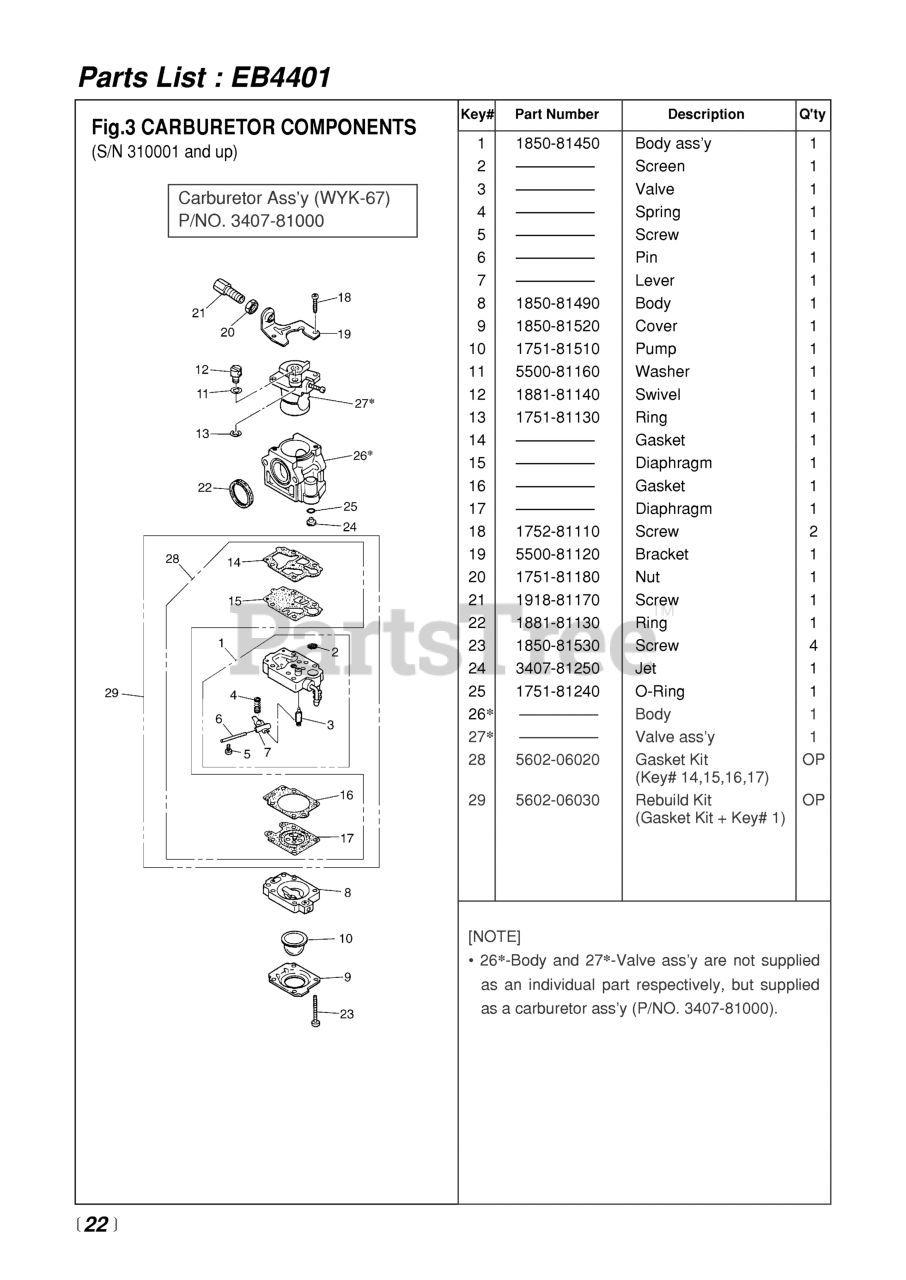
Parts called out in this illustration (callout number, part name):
1	BODY, PUMP
2	SCREEN
3	VALVE
4	SPRING
5	SCREW
6	PIN
7	LEVER
8	BODY, PURGE
9	COVER, PUMP
10	PUMP, PRIMING
11	WASHER
12	SWIVEL
13	RING
14	GASKET
15	DIAPHRAGM
16	GASKET
17	DIAPHRAGM
18	SCREW
20	NUT, CABLE ADJUSTER
21	SCREW, CABLE ADJUSTER
22	RING, PACKING
23	SCREW
25	RING, O
26	CARBURETOR ASSEMBLY
27	CARBURETOR ASSEMBLY
NI	CARBURETOR ASSEMBLY
